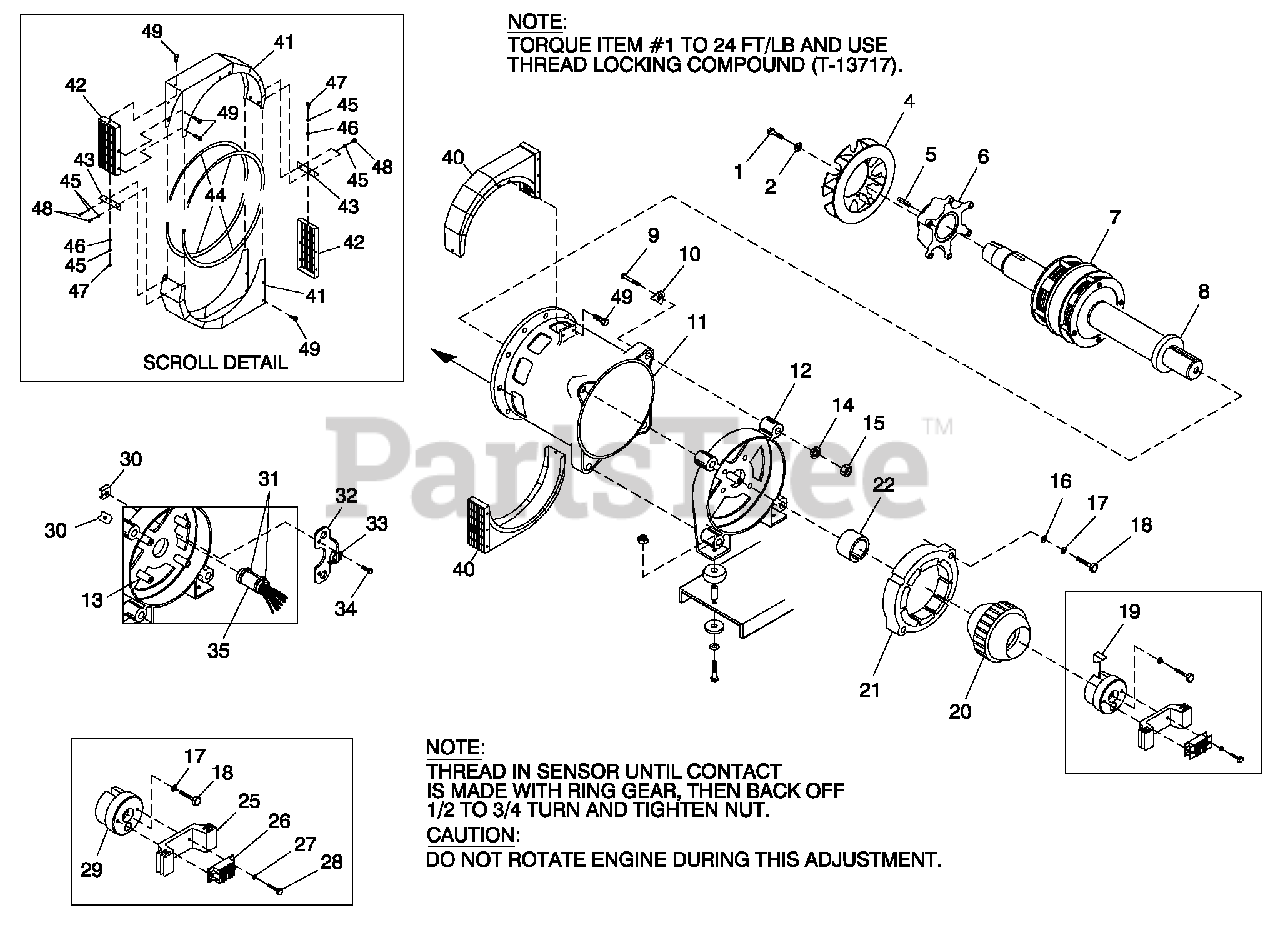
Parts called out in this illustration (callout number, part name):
1	SCREW HHC M8-1.25 X 20 G10.9
2	WASHER LOCK M8-5/16
4	FAN SAE ALTERNATOR (G/B)
5	KEY SQ 3/8X1-9/16 STEEL
6	HU B DRIVE 390 SAE G B
7	RTR 390 100K B3 G B SAE TECHUM
8	BEARING BALL 6212 SEALED
9	SCREW HHC M14-2.0 X 140 G8.8
10	WASHER 390 SAE ALT.
11	STR-390-80LB3 SAE
12	CARRIER REAR BRG 15"
13	PIN DOWEL 1/2 X 1-1/4
14	WASHER LOCK M14
15	NUTHEXM14-2.0 G8 YEL CHR
16	WASHER FLAT M12
17	WASHER LOCK M12
18	SCREW HHC M12-1.75 X 60 G10.9
19	KEY SQ 3/8 X 3-1/4 STEEL
20	ASSY EXCITER 2.00" STK
21	EXITER FIELD 2" LG SPD CONN
22	COLLAR SLIP FIT 390 MM
25	BRIDGE SUPPORT DIODE 15"
26	ASSY BRIDGE RECTIFIER
27	WASHER SHAKEPROOFINT #8
28	SCREW HHM #8-32X7/8
29	CAP END ROTOR 390MM
30	PLATE NUT
31	TIE WRAP UL 14.6 X .14 NATL
32	BRACKET-STATORWIRE
33	CLAMP HOSE #36 1.88-2.7
34	SCREW HHC 5/16-18 X 1-1/4 G5
35	SLEEVE RU BBER
40	ASSY SCROLL 390 SAE
41	SHROUD ALT SHEET METAL
42	SCREEN SHROUD SAE
43	BRKT TENSIONER SAE SCROLL
44	TRIM VINYL BLACK 1/8 GP
45	WASHER LOCK M6-1/4
46	WASHER FLAT 1/4-M6 ZINC
47	SCREW HHC M6-1.0X 25 G8.8
48	SCREW HHC M6-1.0X 16 G8.8
49	SCREW SWAGE 1/4-20 X 1/2 ZYC
